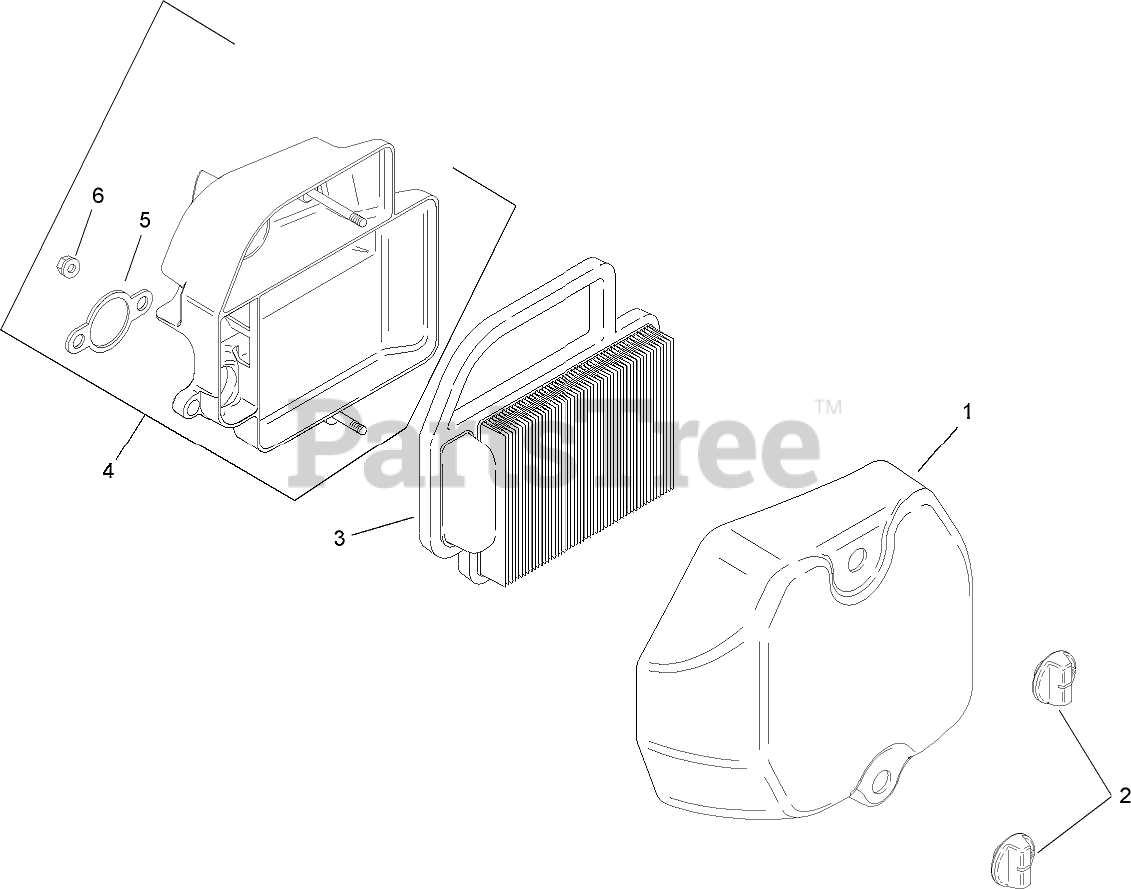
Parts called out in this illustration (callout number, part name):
1	AIR CLEANER COVER ASM
2	KNOB-COVER
3	Element-Air Cleaner
4	Air Cleaner Base Kit (Includes 5-6)
5	Gasket-Base, Air Cleaner
6	NUT-FLANGE (M6X1.0)
